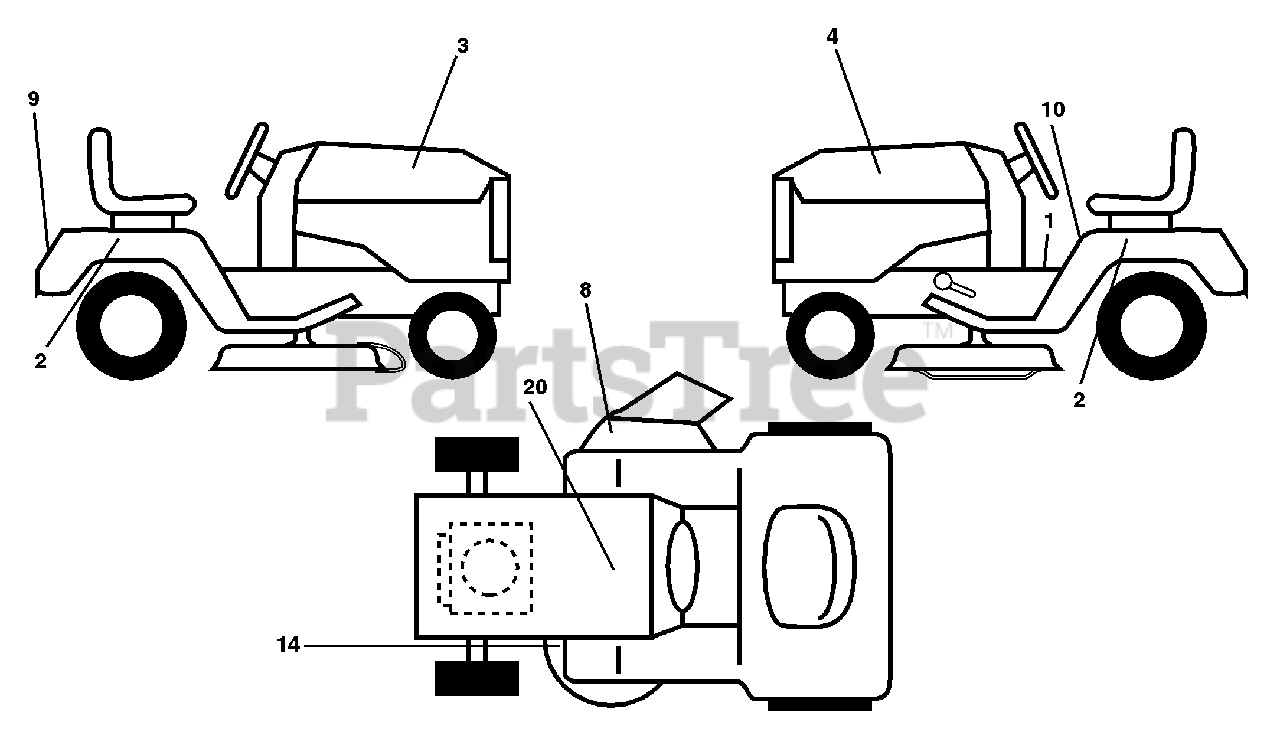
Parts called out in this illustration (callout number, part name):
1	Decal Oper Step Thru E/F
2	Decal Fender Auto Husq. Radius
3	Decal Hood LH
4	Decal Hood RH
8	Decal Warning
9	Decal Fender Husq
10	Decal Fender Danger E/F
14	Decal V-Belt Schematic
20	Decal Bat Dan/Psn
